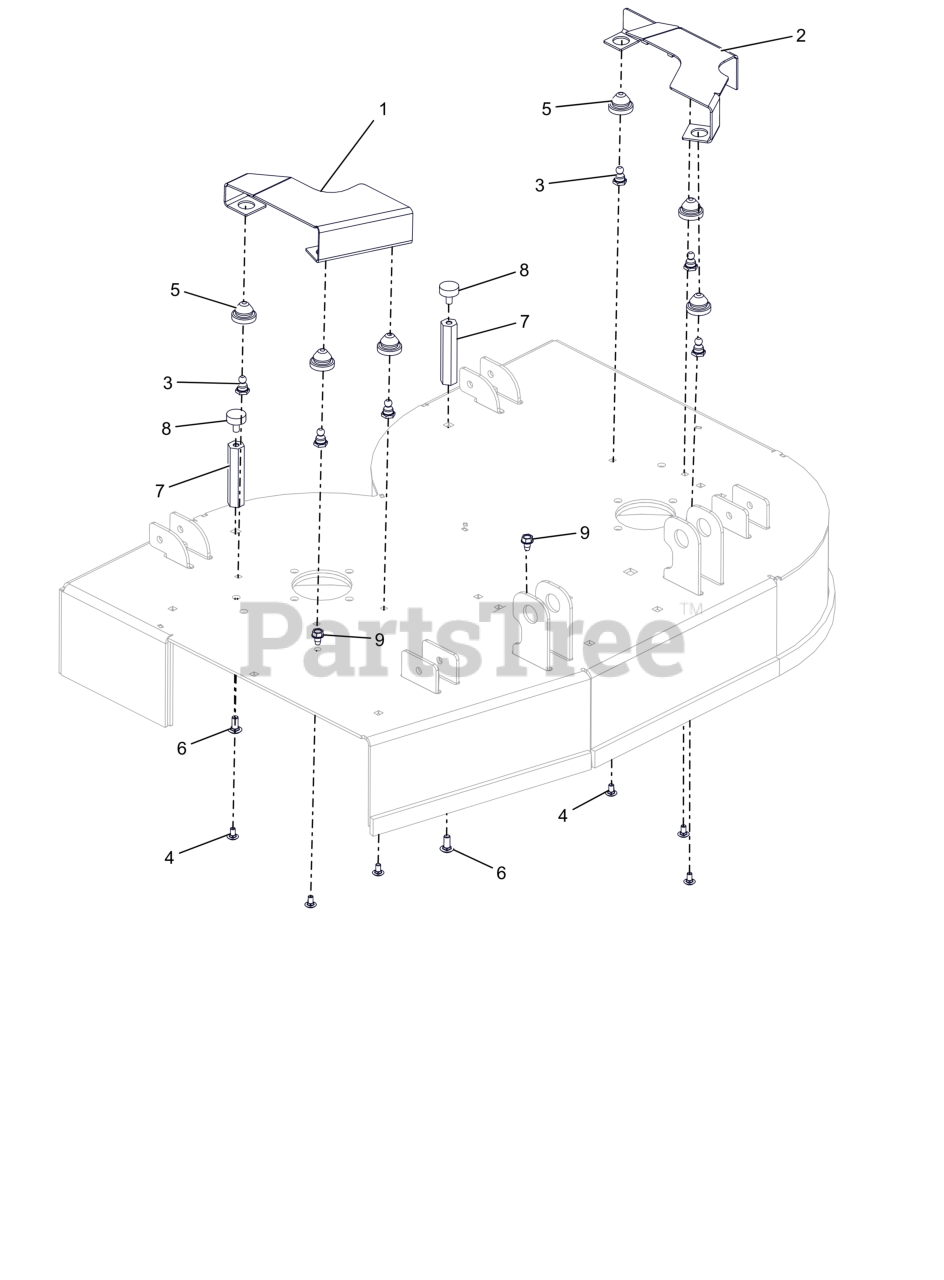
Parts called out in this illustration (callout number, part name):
1	GUARD, RH DECK BELT (RED)
2	GUARD, LH DECK BELT (RED)
3	STUD, BALL FEMALE .250-20 THREAD
4	BLT, RHSSN.25-20X.500 G5 ZCC
5	COUPLING, RUBBER PUSH-IN
6	BLT, RHSSN.31-18X.750 G5 ZCC
7	NUT, .31-18 x 3.500 LG COUPLING
8	BUMPER, RUBBER
9	SCR,TAP .312-18X.50 HWH TR ZCC
